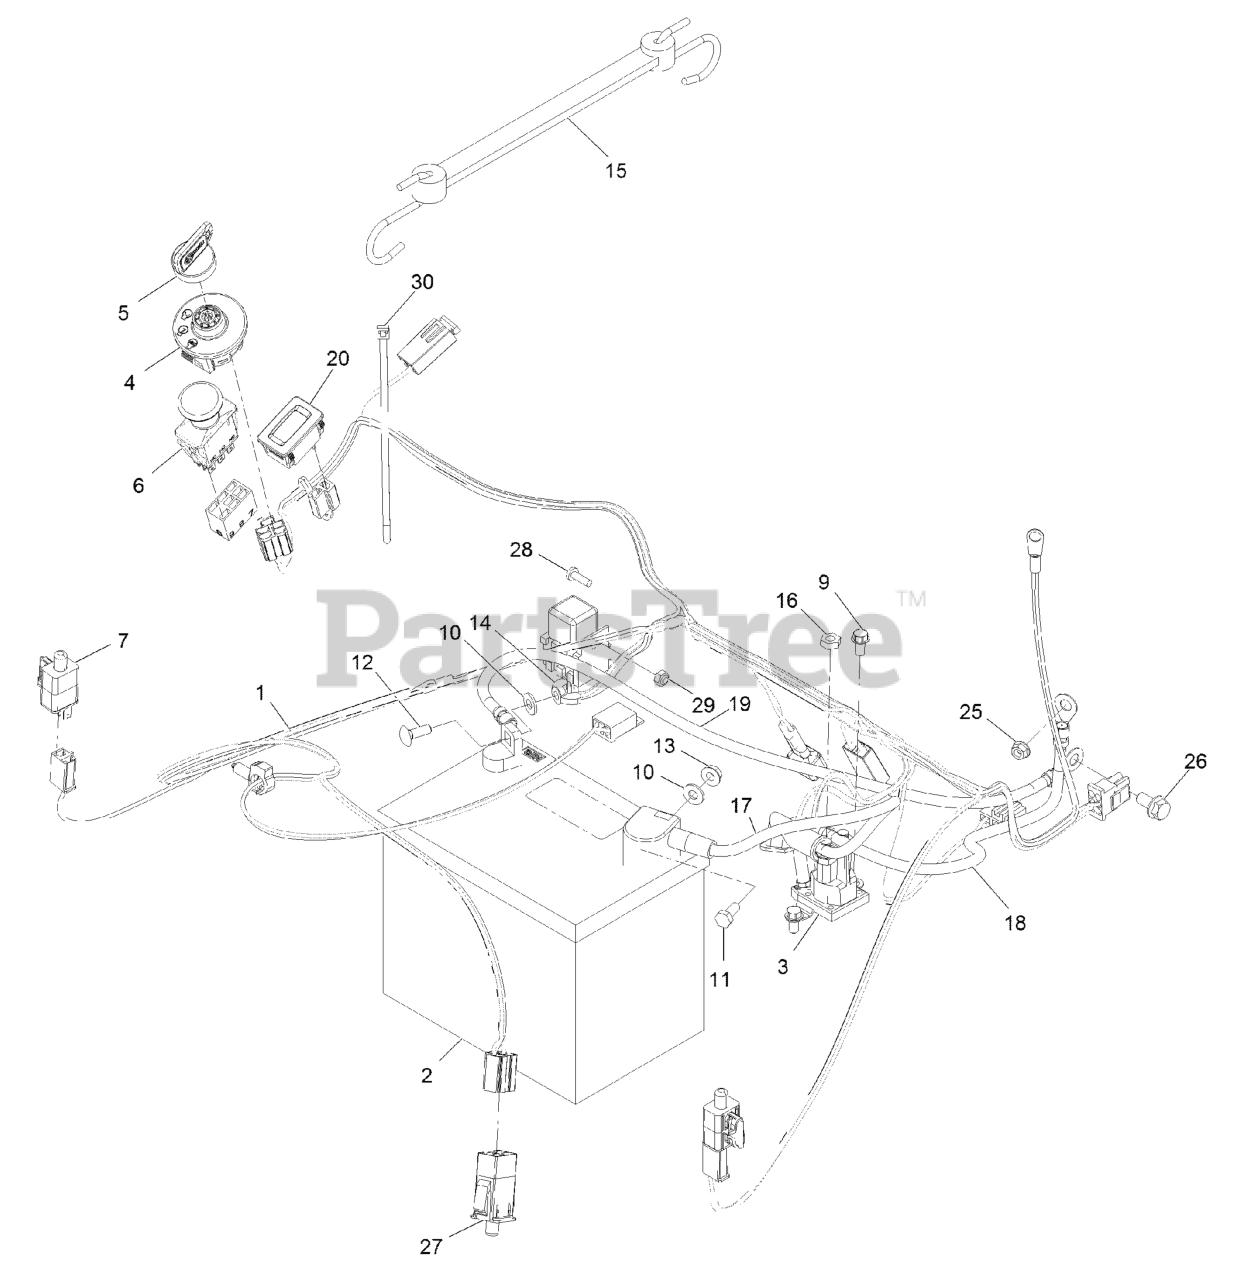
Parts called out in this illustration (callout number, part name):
1	HARNESS-WIRE
2	BATTERY
3	SOLENOID
4	SWITCH-IGNITION
5	KEY-IGNITION
6	SWITCH-PTO
9	SCREW-HWH
10	WASHER-FLAT
11	SCREW-HH
12	BOLT-CARR
14	NUT-WING
15	HOLDDOWN-BATTERY
16	NUT-JAM
17	CABLE-BATTERY, RED
18	CABLE-BATTERY, POSITIVE
19	CABLE-BATTERY, BLACK
20	HOURMETER
26	SCREW-HHF
27	SWITCH-DELTA
28	SCREW-PPH
29	NUT-LOCK, NI
30	TIE-CABLE
